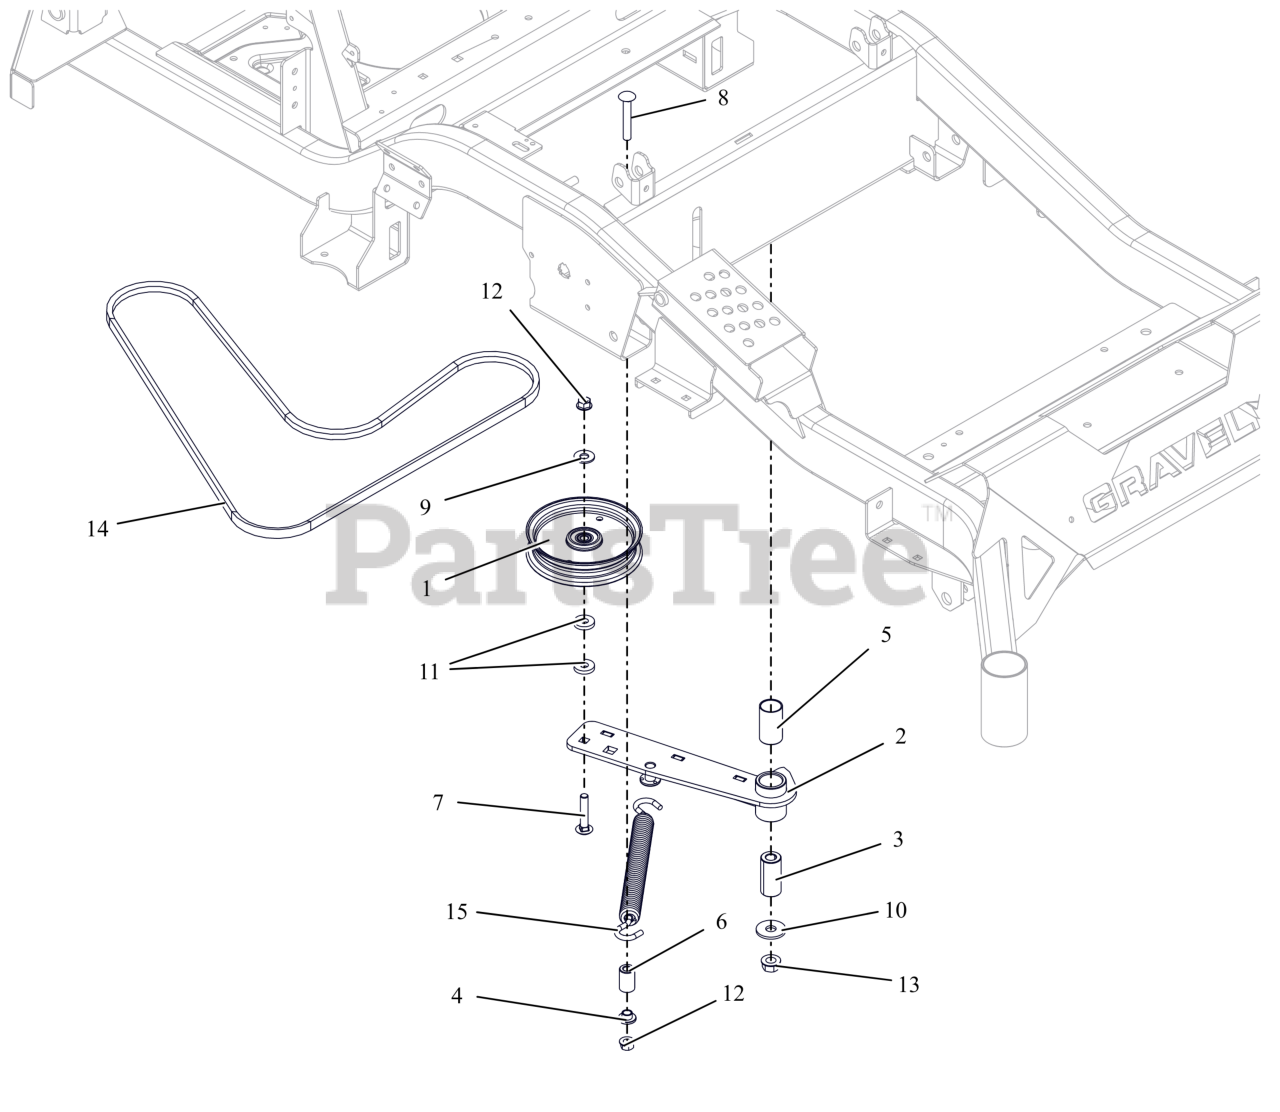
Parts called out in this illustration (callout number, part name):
1	IDLER- FLAT - 5.00" X .75"
2	WLDMT, HYDRO DRIVE IDLER ARM (BLACK)
3	BSHG, SPCR .502X.997X2.03 PM
4	BSHG-FLG .385X.500X.875X.406
5	BSHG, 1.00X1.125X1.937
6	BUSHING, SLV .380X.750X1.190
7	BLT, RHSN .38-16X2.00 G5 ZCC
8	BLT, RHSSN.38-16X2.50 G5 ZCC
9	WSHR,FLT .438X1.00X.083 ZCC
10	WSHR-FL-STL.511X1.44X.125ZC120
11	WSHR, FLT .406X1.00X.188 ZCC
12	NUT-LK-TOP-FLG .38-16 ZC120
13	NUT-LK-TOP-FLG .500-13 GF ZCC
14	V-BELT, 4L-WRAPPED
15	SPRING, EXTENSION
